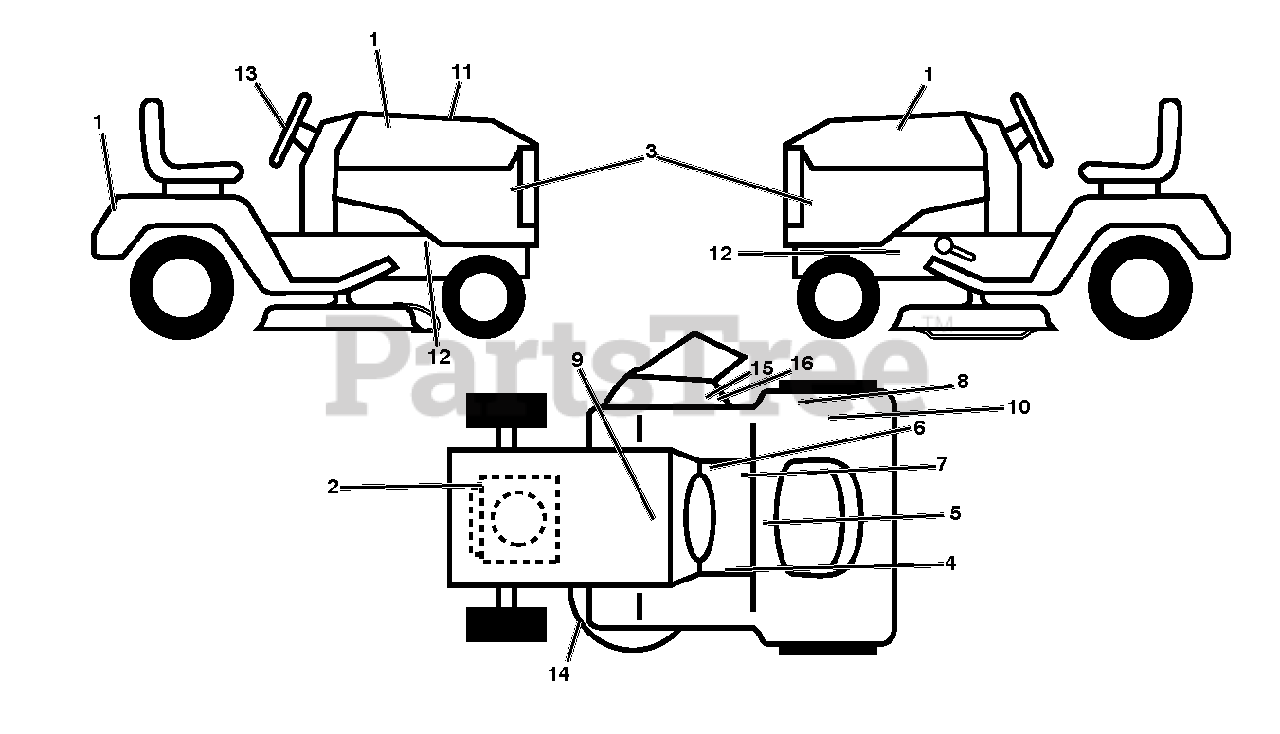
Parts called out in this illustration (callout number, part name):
1	DECAL, DIXON LOGO, DOMED
3	DECAL.SDPNL.22/42.KOHLER.DIX
9	DECAL BTRY SYMBOLS
13	DECAL.WHEEL.STEER.DIXON
14	DECAL V BELT SCHEMATIC
15	DECAL, DEFLECT WARNING
